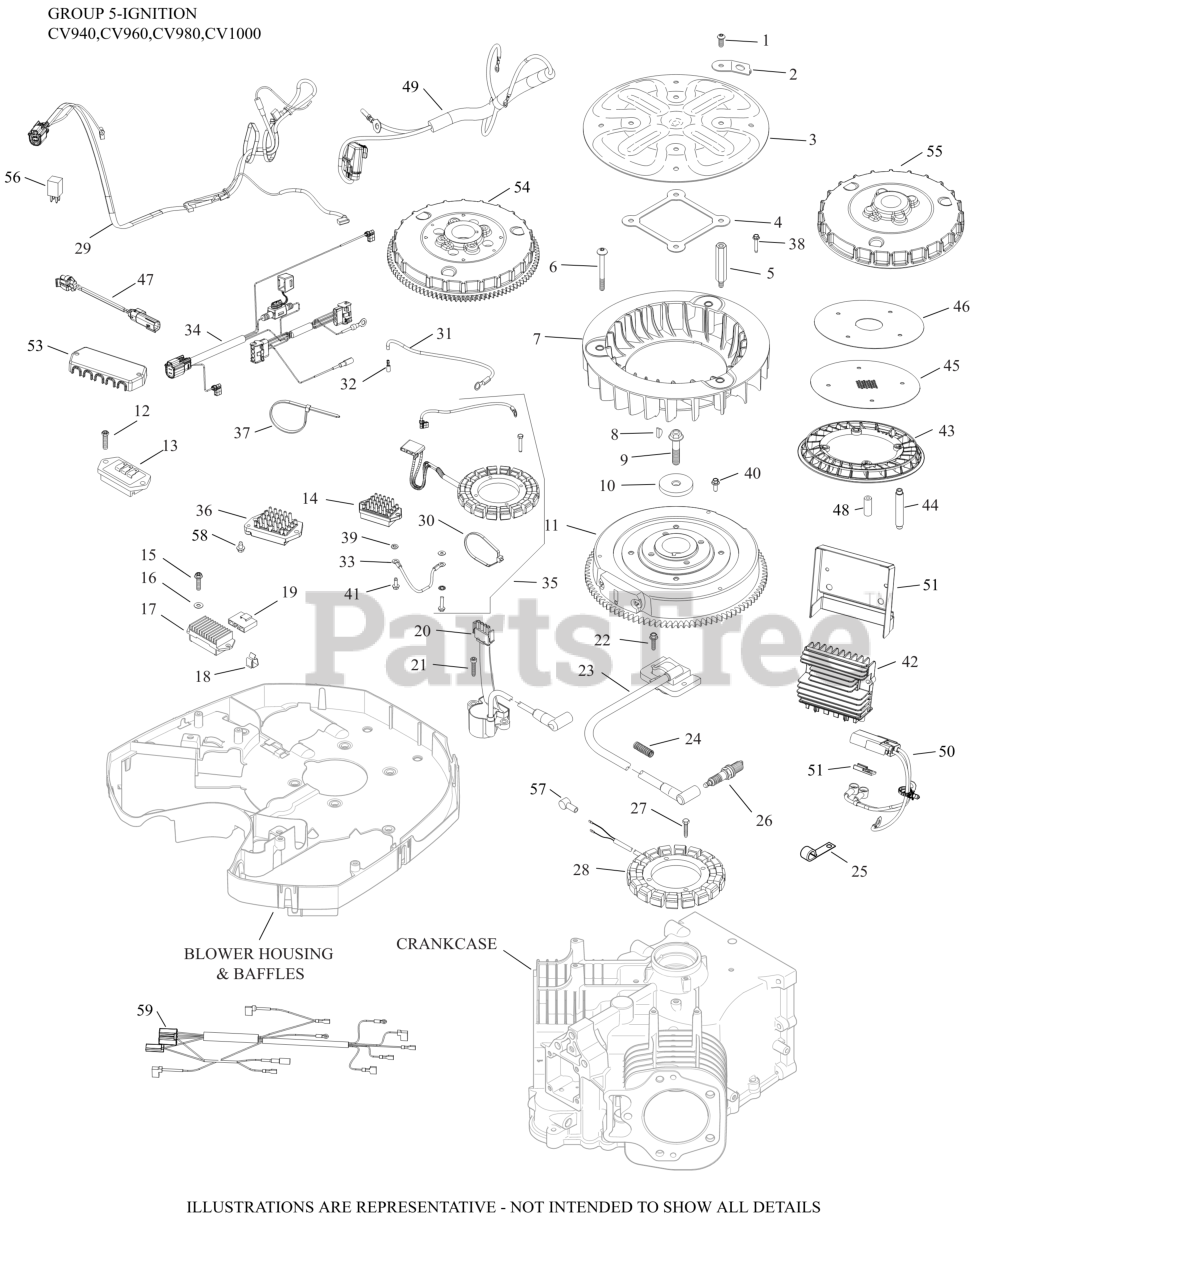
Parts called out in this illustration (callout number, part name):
2	PLATE, GRASS SCREEN WASHER
3	KIT, GRASS SCREEN
4	STIFFENER, GRASS SCREEN
5	STUD, GRASS SCREEN
6	SCREW, TRS HD M6X1.0X65
7	KIT, FAN AND SPACERS
8	KEY, 3/16" X 5/8"
9	SCREW, FLG M10X1.5X45-USE 25 086 361-S
10	WASHER, FLAT 13/32"
11	FLYWHEEL ASSEMBLY
15	SCREW, HEX FLANGE HI-LO
19	CONNECTOR
23	MODULE, IGNITION
24	SLEEVE, CORRUGATED
25	CLIP, CABLE
26	PLUG, SPARK
27	SCREW, THREAD FORMING
28	KIT, 15 / 20 AMP STATOR
29	HARNESS, WIRING
30	TIE, CABLE
31	LEAD, B+ TO STARTER SOLENOID
33	KIT, GROUND, LEAD
36	REGULATOR, RECT (20-30AMP, FW W/OVP)
38	SCREW, THREAD THROWING
40	SCREW,HEX FLNGE
41	SCREW, THREAD FORMING
